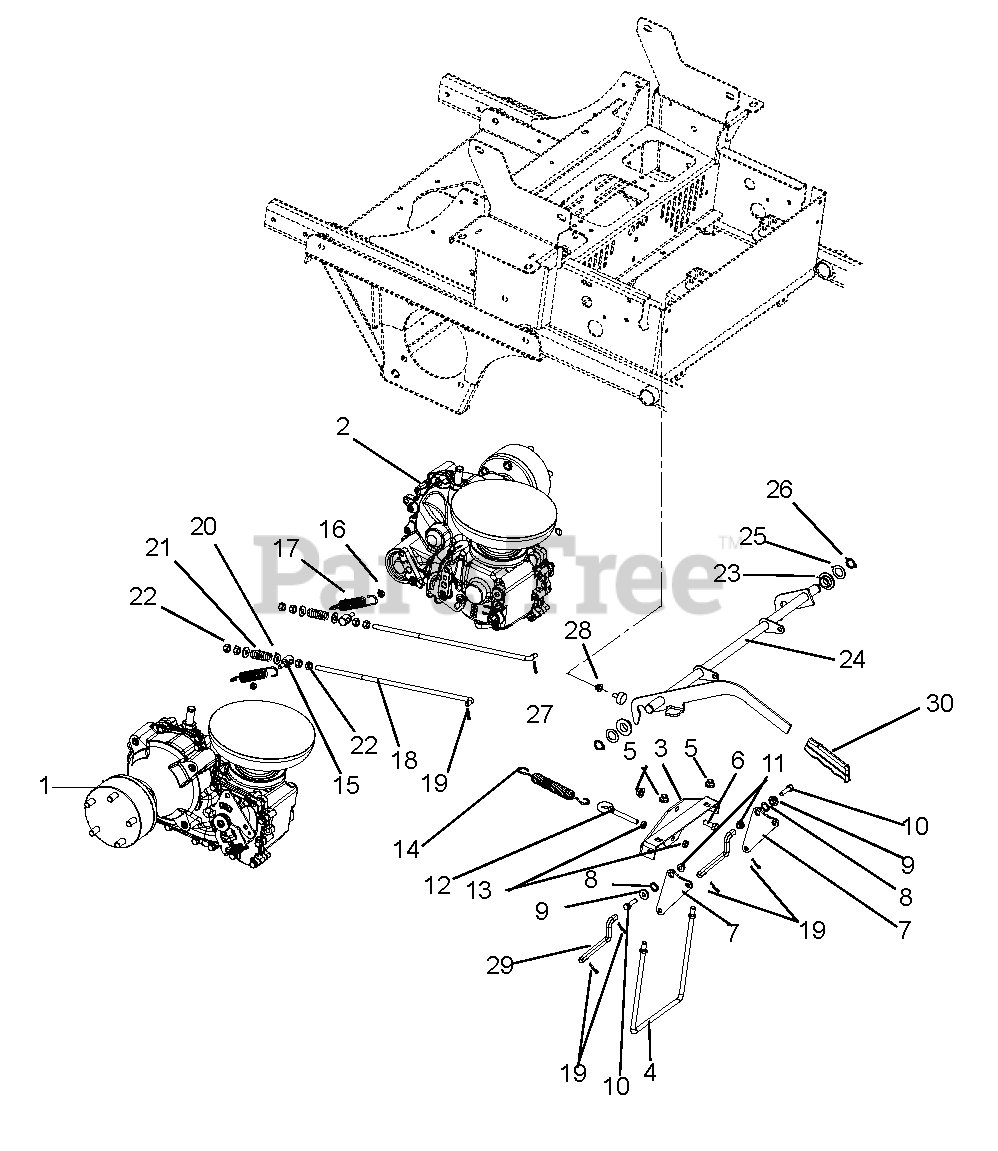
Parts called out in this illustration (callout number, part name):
1	Transmission, Right Hand HG ZT-5400
2	Transmission, Left Hand HG ZT-5400
3	Weldment, Spring Anchor Bracket
4	Rod, Brake Mounting
5	Nut, Locking Nylon-Flange .38-16 YWZC
6	Bolt, Hex .38-16 x 1.00 GR5 YWZC
7	Plate, Brake Pivot
8	Wave Washer .531 x .781 x .125FH
9	Bushing-Flange .32 x .500 x .344 x .880
10	Bolt-Hex .31-18 x 1.25 GR5 YWZC
11	Nut, Locking Nylon-Flange .31-18 YWZC
12	Bolt, Eye .375-16 x 2.50 YWZC
13	Nut, Hex-JAM .375-16 YWZC
14	Sping, Extension
15	Trunnion, .38-16
16	Nut, Locking Center-Jam .31-18 YWZC
17	Spring, Tension .105 x .85 x 5.00 WLD 40
18	Rod, Brake Adjustment
19	Pin, Hair
20	Washer, Flat Steel.38 x .875 x .083 YWZC
21	Spring, Compression .142 x .710 x 1.75
22	Nut, Hex .38-16 YWZC
23	Bushing, Flange .762 x 1.48 x .44 NYL
24	Weldment, Brake Interlock
25	Washer, Hardened Thrust .758 x 1.23 x .031
26	Ring, Retaining-EXT .689 x .078
27	Bumper, Rubber
28	Nut, Spin Lock-Flange .312-18 YWZC
29	Linkage, Brake Actuating
30	Grip, Parking Brake (Yellow)
